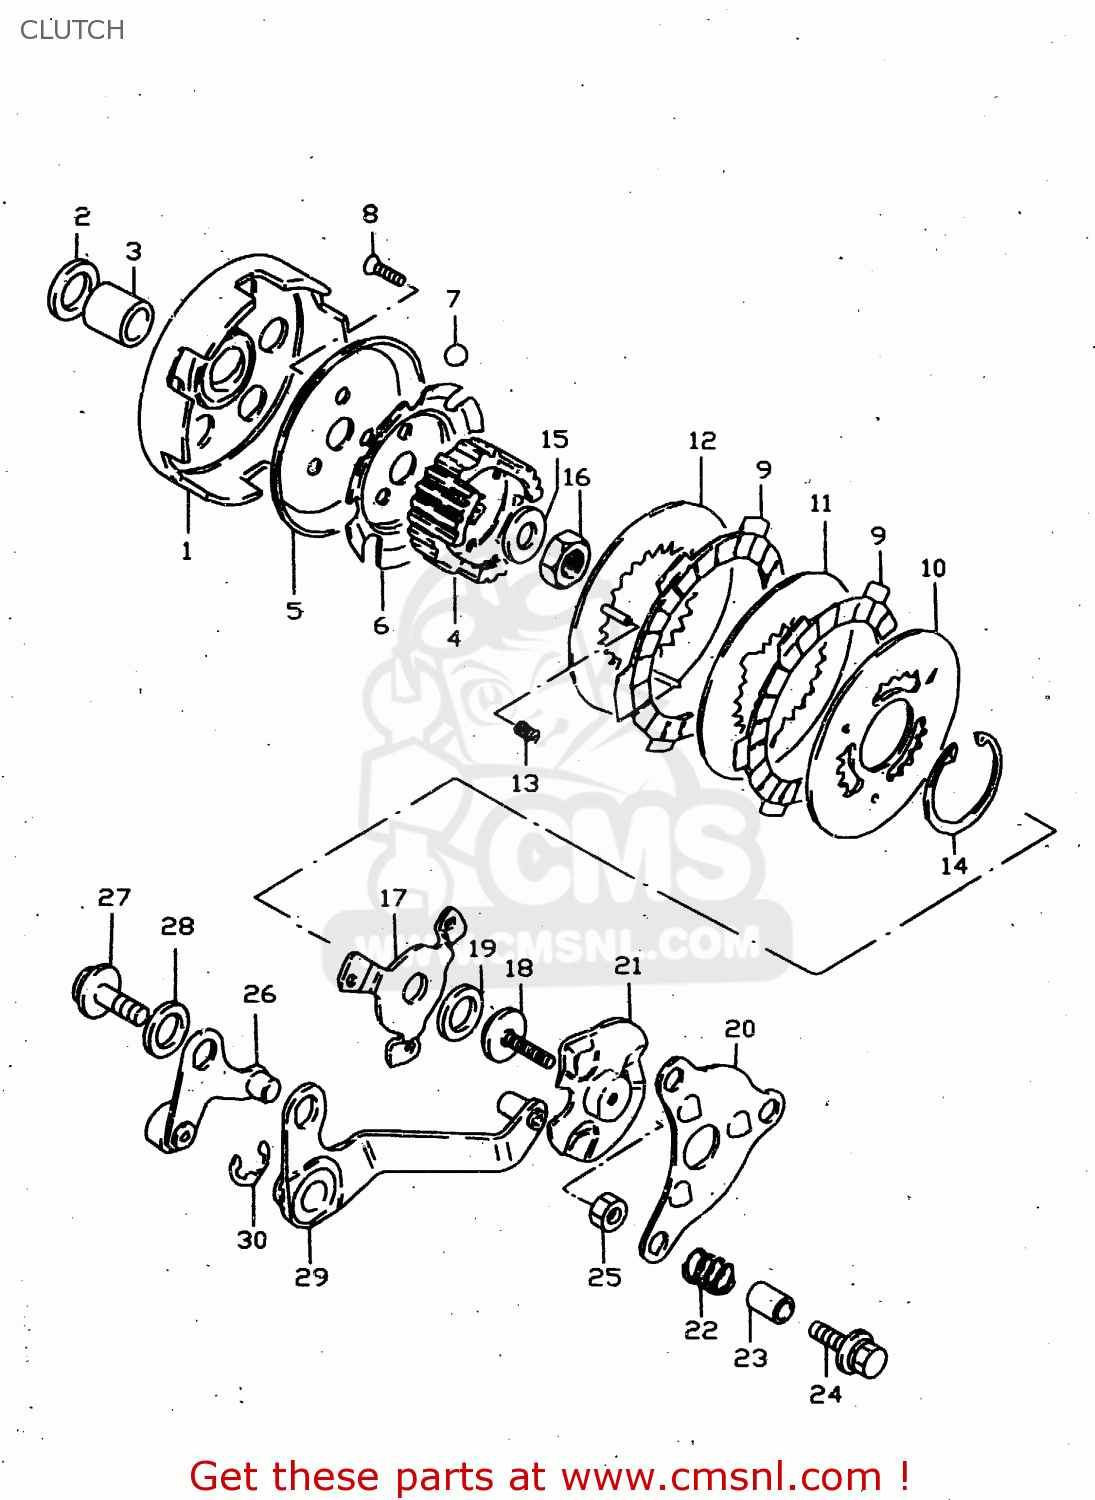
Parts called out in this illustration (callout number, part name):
1	GEAR,PRIMARY DRIVE
2	WASHER(14X23X3)
3	SPACER(14X19X18)
4	HUB,CLUTCH SLEEVE
5	PLATE,CLUTCH BALL
6	GUIDE,CLUTCH BALL
7	BALL
8	SCREW ,6X16
9	PLATE,CLUTCH DRIVE (NAS)
10	PLATE,CLUTCH DRIVEN OUTER (NAS)
11	PLATE,CLUTCH DRIVEN (NAS)
12	PLATE,CLUTCH INNER
13	SPRING
14	CIRCLIP
15	WASHER
16	NUT
17	PLATE,CLUTCH PRESSURE
18	PIECE,CLUTCH PUSH
19	BEARING(10X22X2.8)
20	PLATE,CLUTCH RELEASE
21	PLATE,CLUTCH RELEASE,INNER
22	SPRING
23	SPACER(6X9X10.3)
24	BOLT
25	NUT 6MM
26	PLATE,CLUTCH RELEASE ARM LINK
27	BOLT(8X17)
28	WASHER
29	ARM,CLUTCH RELEASE PLATE
30	E RING
